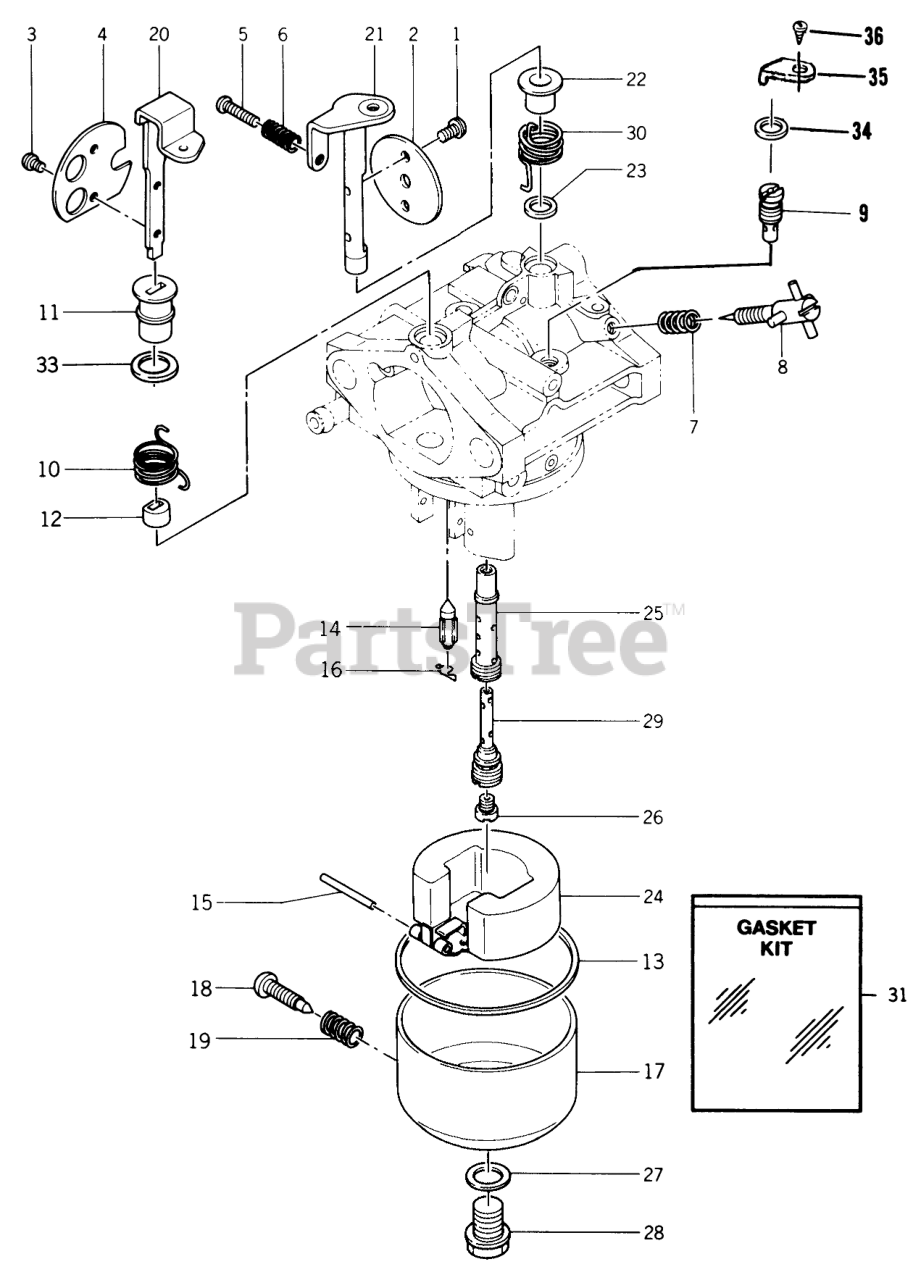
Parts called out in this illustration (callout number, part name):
1	SCREW-THROTTLE PLATE
2	VALVE THROTTLE
3	SCREW
4	VALVE CHOKE
5	SCREW
6	SPRING IDLE
7	SPRING
8	Adjuster Screw
10	SPRING
12	COLLAR
13	GASKET
14	Needle Valve Assy
15	PIN-FLOAT
17	Assy.-Chamber, Float (Incl. Ref. #18 & 19)
18	SCREW-DRAIN
19	SPRING
20	SHAFT-CHOKE
21	Shaft-Throttle
22	RING BUSHING
23	Seal
24	FLOAT
25	NOZZLE-MAIN
26	JET MAIN
27	GASKET
29	HOLDER-MAIN JET
30	Spring
31	Carburetor Gasket Set
34	PLATE
35	Screw
36	JET-PILOT
37	O-RING
